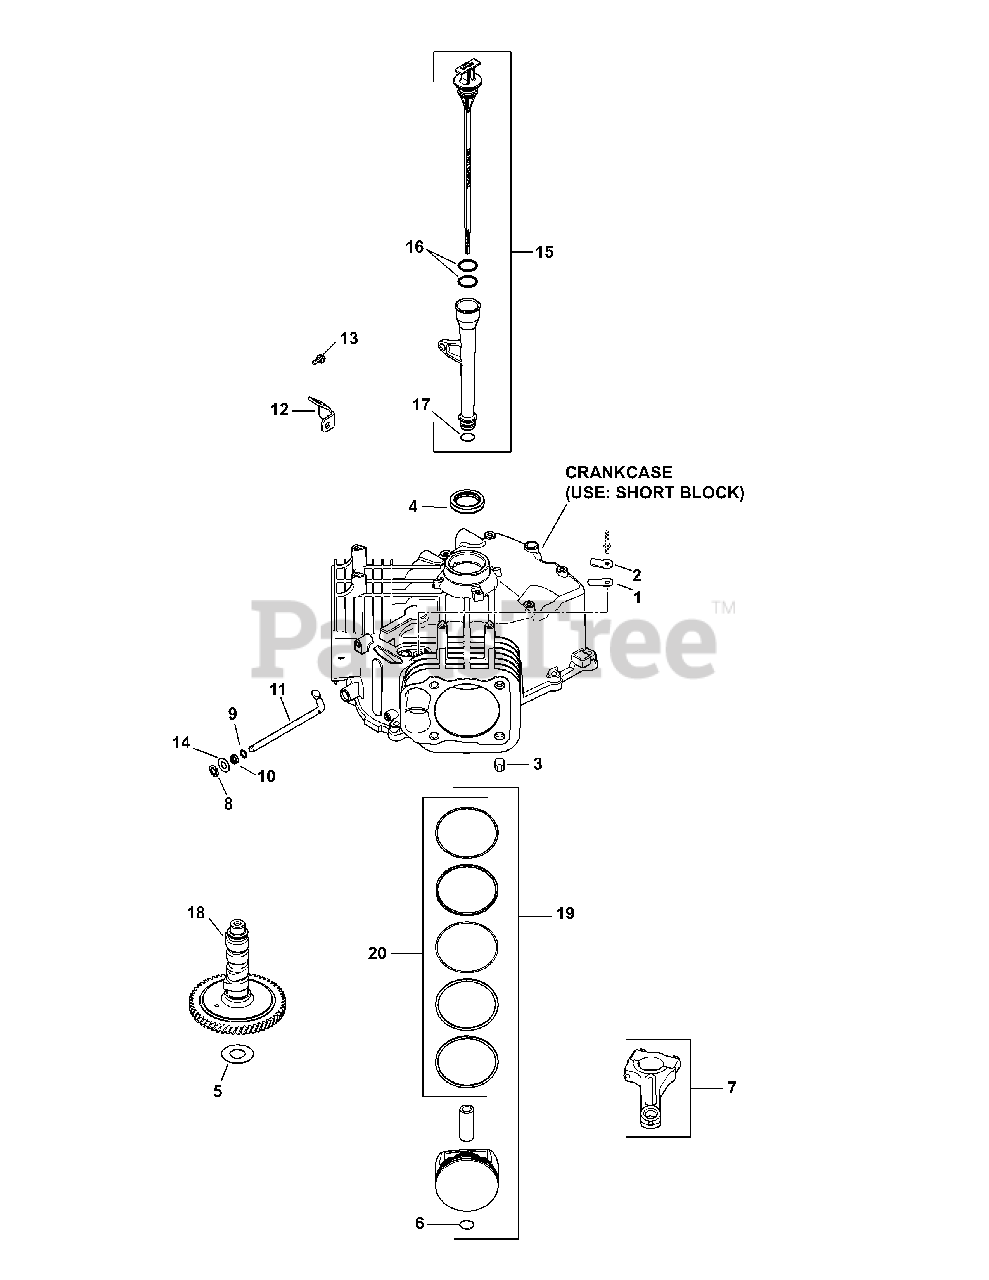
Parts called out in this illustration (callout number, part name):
1	Breather Reed
2	Breather Reed Retainer
4	Oil Seal (Helix Lip)
5	Camshaft Shim (White .028")
5	Camshaft Shim (Blue .03")
5	Camshaft Shim (Red .032")
5	Camshaft Shim (Yellow .034")
5	Camshaft Shim (Green .036")
5	Camshaft Shim (Gray .038")
5	Camshaft Shim (Black .04")
6	Piston Pin Retainer
7	Connecting Rod (Std)
8	Ring Retainer
9	Flat Washer, 11/32
10	Governor Cross Shaft Seal
11	Governor Cross Shaft
12	Oil Fill Tube Bracket
13	Flg. Thd. Frm. Screw, M5 x 0.8 x 13
14	Flat Washer, 9mm
15	Dipstick And Tube Kit
16	Dipstick O-Ring
17	O-Ring, Lower Oil Fill Tube
18	Camshaft Assembly
19	Piston Kit w/ Ring
19	Piston Kit w/ Ring (0.25) 83mm
19	Piston Kit w/ Ring (0.08) 83mm
20	Ring Set, Piston STD
20	Ring Set, Piston (.08)
20	Ring Set, Piston (.25)
